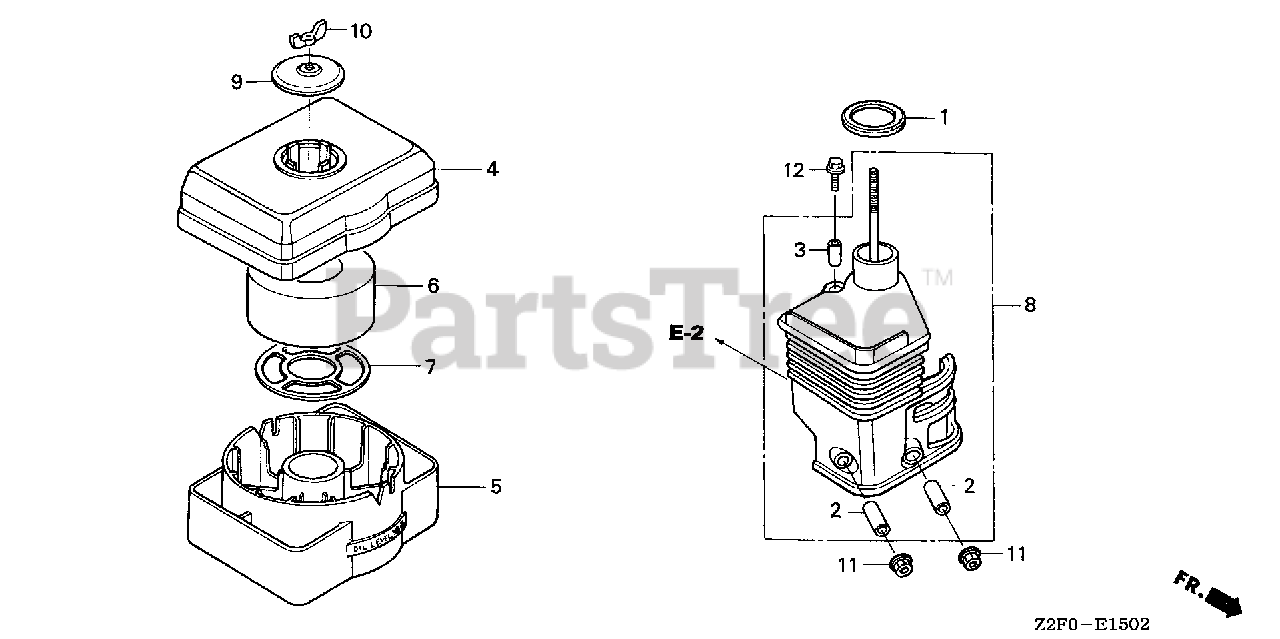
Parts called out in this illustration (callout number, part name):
1	GASKET, ELBOW
2	COLLAR, AIR CLEANER
3	COLLAR B, AIR CLEANER
4	BODY, CLEANER (OIL BATH)
5	PAN, CLEANER OIL (OIL BATH)
6	ELEMENT, AIR CLEANER (OIL BATH)
7	GRID, AIR CLEANER
8	ELBOW, AIR CLEANER
9	CAP, CLEANER
10	NUT, TOOL BOX SETTING
11	NUT, FLANGE (6MM)
12	BOLT, FLANGE (6X20)
